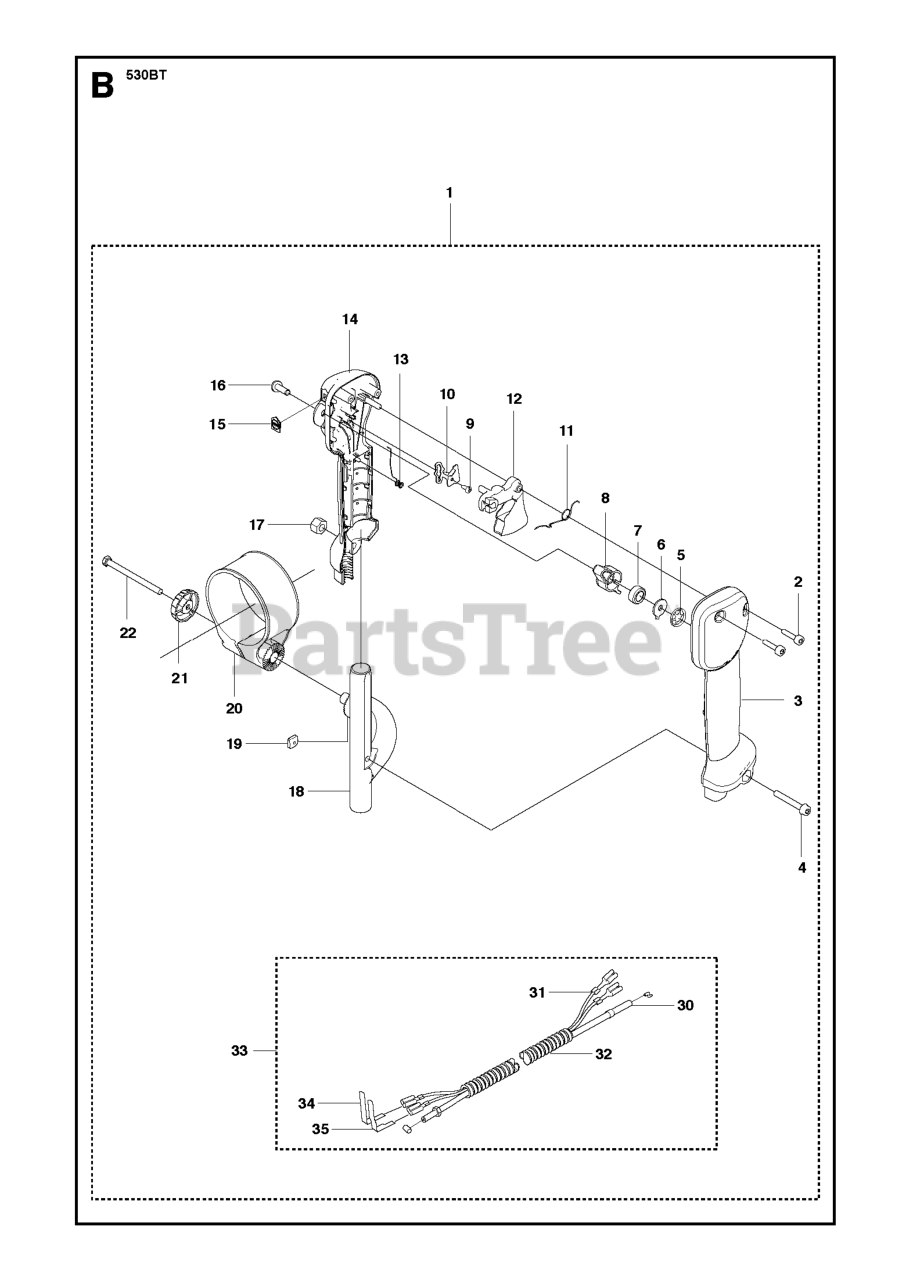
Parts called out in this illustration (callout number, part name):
1	HANDLE ASSY
2	SCREW
3	HANDLE HALF (R)
7	SPRING RUBBER
8	LEVER STOP
12	TRIGGER 848L5W34C0
14	HANDLE HALF (L)
16	SHAFT PIVOT
18	HOLDER, HANDLE
19	SQUARE NUT M5
21	KNOB
31	RP CORD
33	WIRING ASSY 130BT
34	CONTACT SPRING
35	CONTACT SPRING
